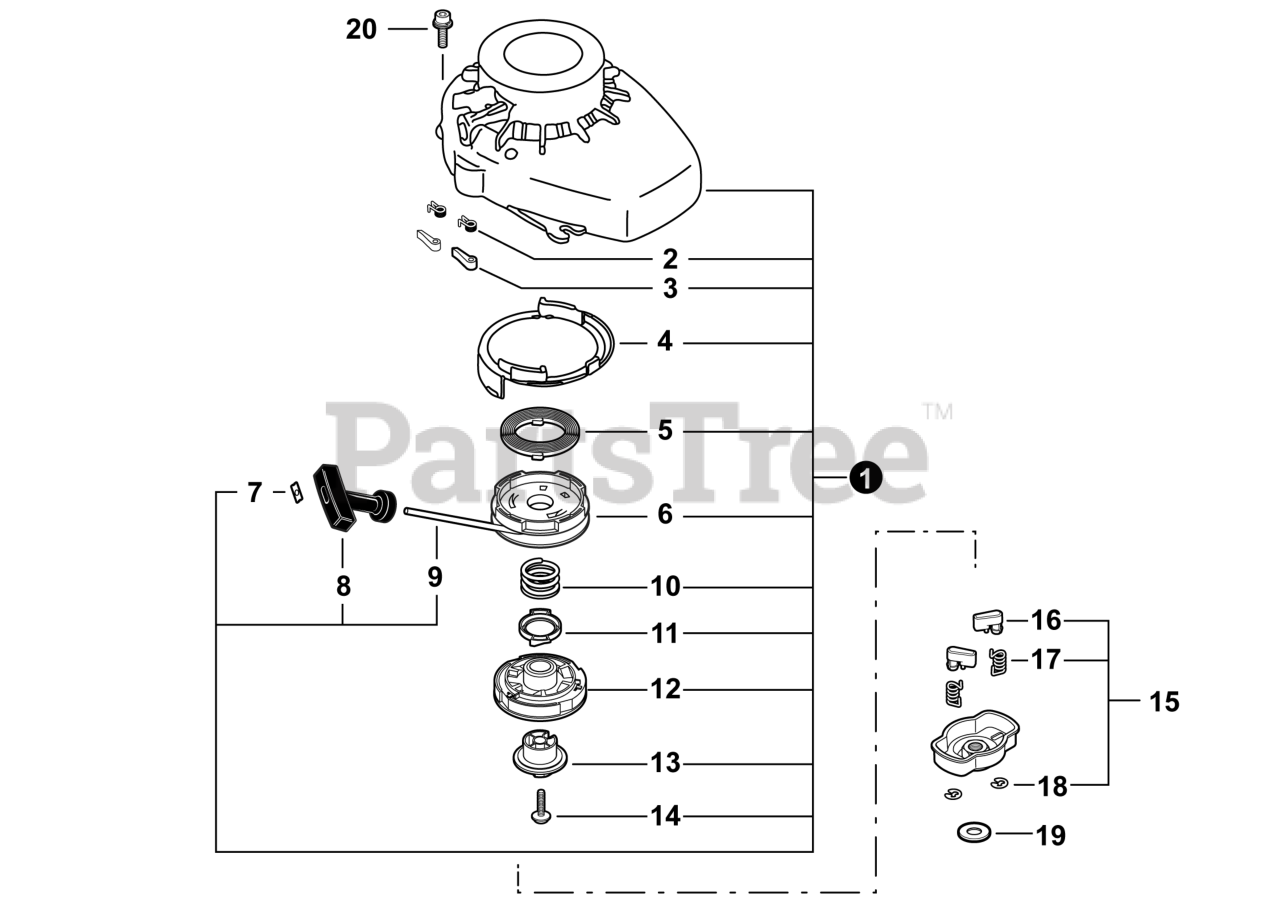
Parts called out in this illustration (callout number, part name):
1	STARTER ASSY
3	PAWL, STARTER
4	CASE, STARTER
5	SPRING, RECOIL
6	PULLEY, STARTER
7	RETAINER, ROPE
8	GRIP, STARTER
9	ROPE, STARTER
10	SPRING, RETURN
11	PAWL, STARTER
12	SPRING ASSY
13	PLATE, CAM
15	PAWL ASSY, STARTER
16	PAWL, STARTER
17	SPRING, RETURN
18	E-RING 4
19	WASHER, SPRING 8
20	SCREW 4x16
